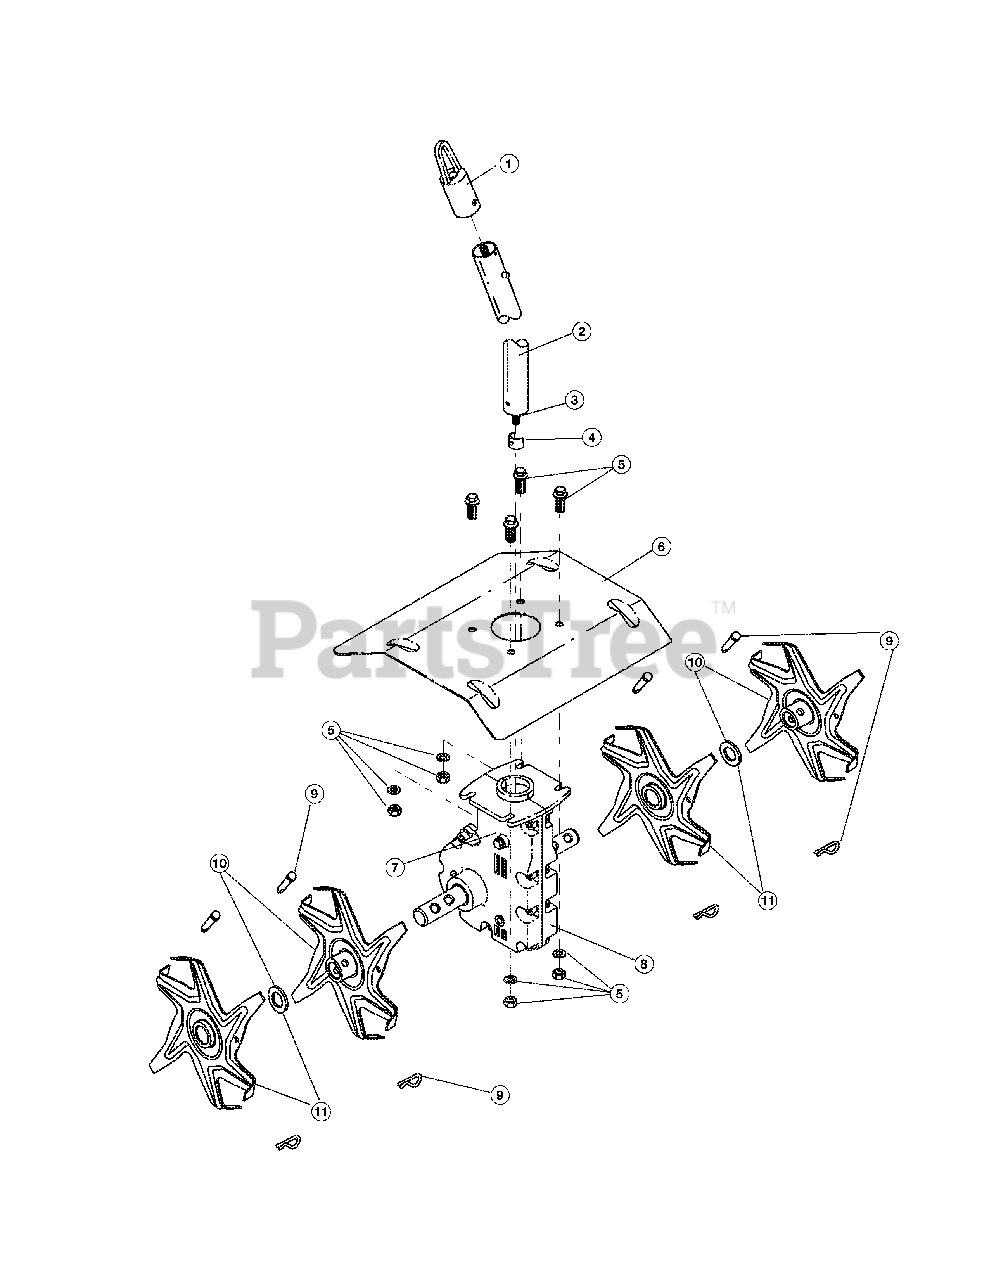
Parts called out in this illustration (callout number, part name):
1	Accessory Hanger
2	Drive Shaft Housing Assembly
3	Flexible Drive Shaft
4	Retainer Sleeve
5	Guard Mounting Hardware Set
7	Bolt
8	Gear Box Assembly
9	Tine Fastener Assembly
10	Tine Assembly (Left Outer or Right Inner)
11	Tine Assembly (Left Inner or Right Outer)
